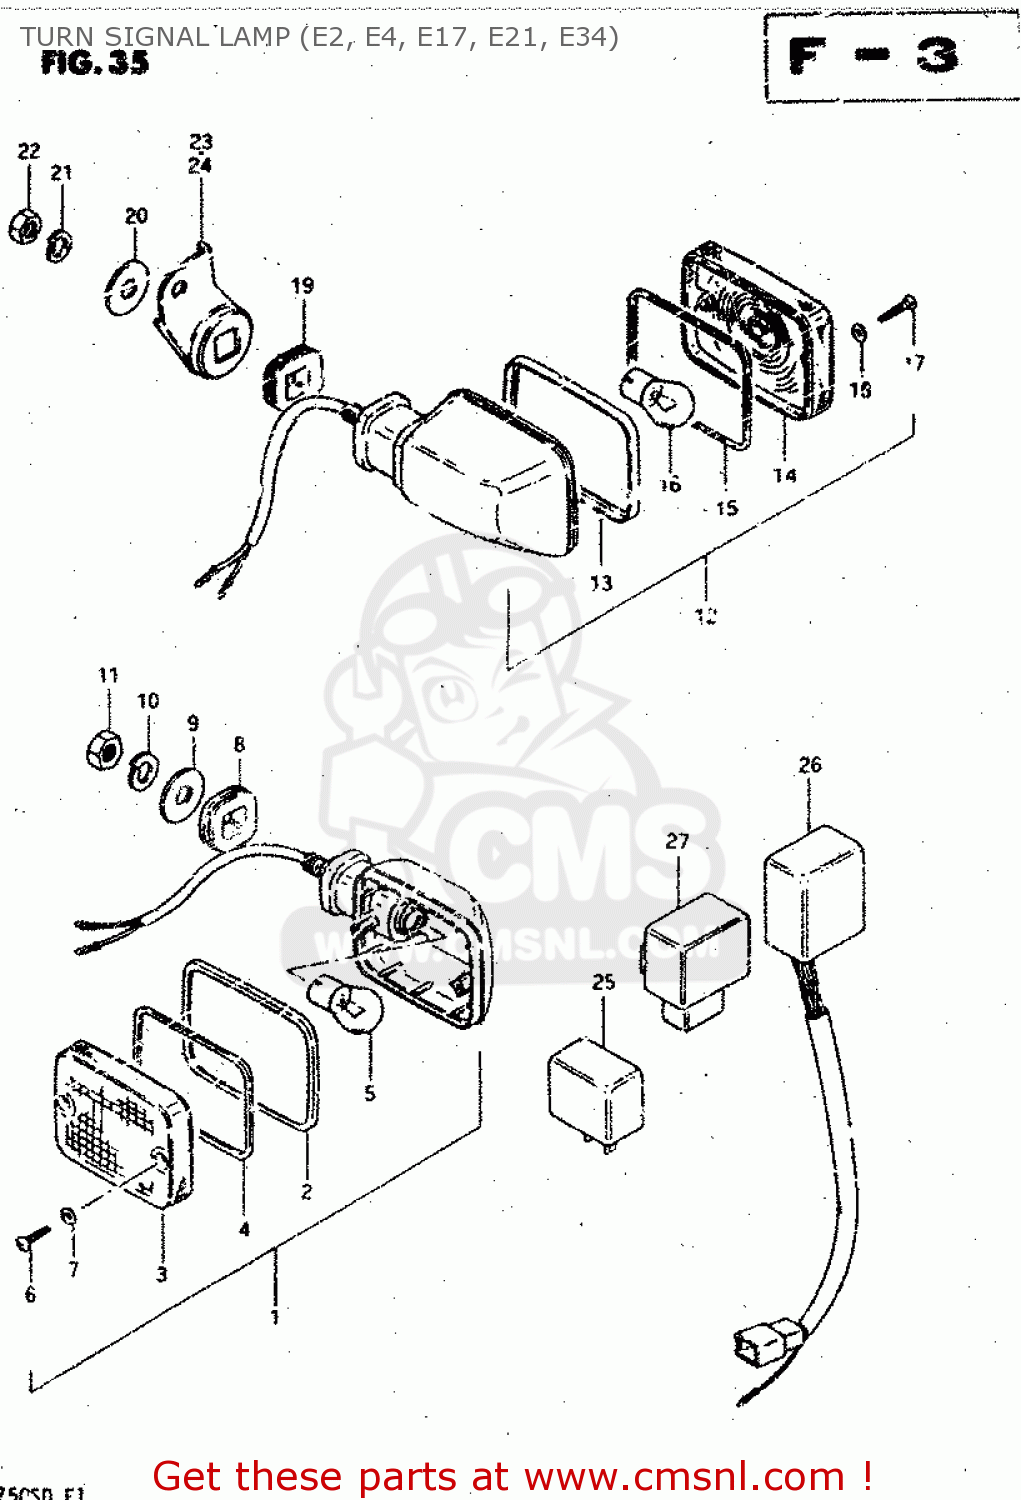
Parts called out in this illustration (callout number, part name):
1	LAMP ASSY,FR T
2	RIM
3	LENS
4	GASKET (NAS)
5	BULB(12V21W)
6	SCREW
7	GASKET (NAS)
8	CUSHION
9	WASHER (10.5X30X2.3)
10	LOCK WASHER
11	NUT
12	LAMP, REAR TURN SIGNAL
13	RIM
14	LENS
15	GASKET (NAS)
16	BULB(12V21W)
17	SCREW
18	GASKET (NAS)
19	CUSHION
20	WASHER (10.5X30X2.3)
21	LOCK WASHER
22	NUT
23	BRACKET,RR TURNSIGNAL LAMP,R
24	BRACKET,RR TURNSIGNAL LAMP,L
25	RELAY ASSY,TURNSIGNAL
26	UNIT,TURN SIGNAL CONTROL
27	UNIT,TURN SIGNAL CONTROL
